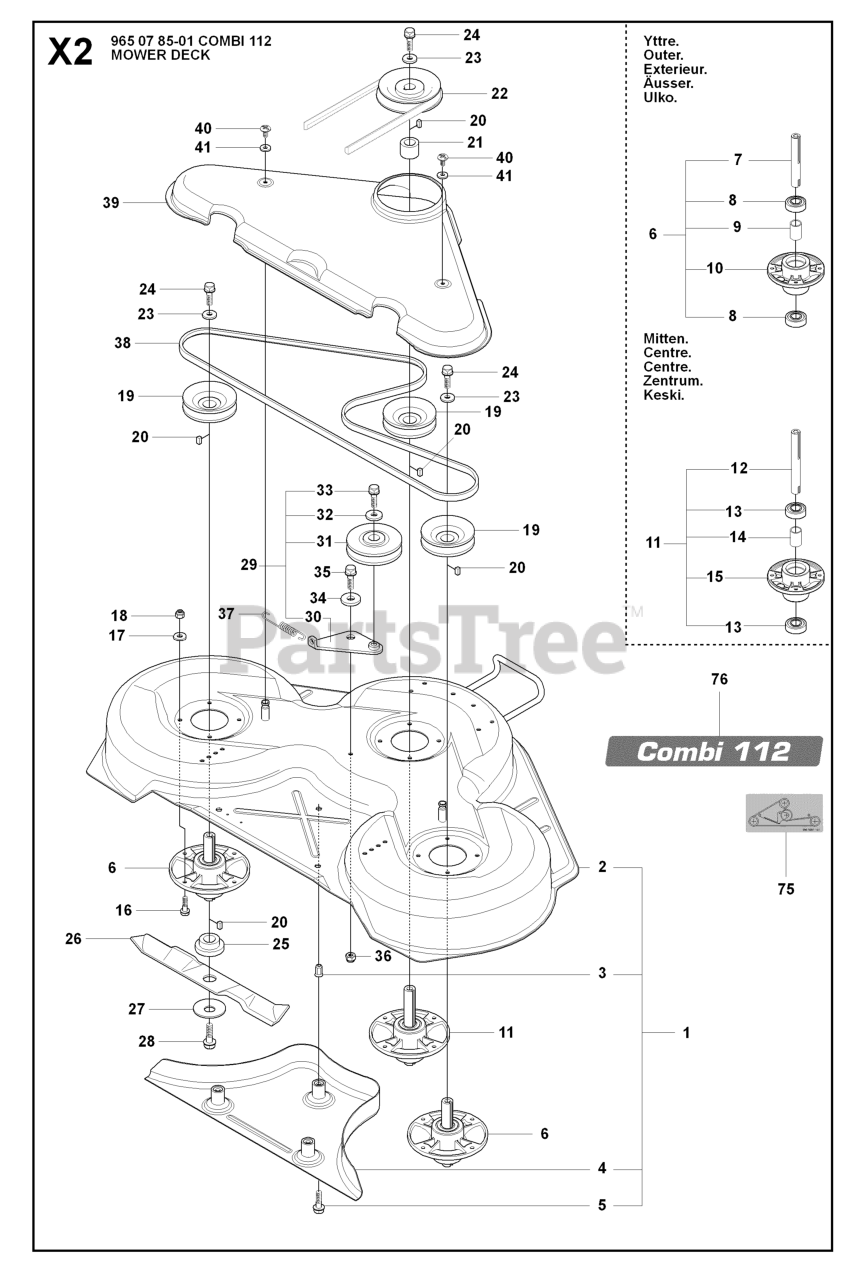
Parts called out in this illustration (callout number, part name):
1	CUTTING DECK C112 GREY RIDER
2	CUTTING DECK ASSY C112 GREY
6	RP SPINDLE ASSY
10	BEARING HOUSING
11	SPINDLE ASSY
15	BEARING HOUSING
17	WASHER BRB 8.4X17
18	LOCKNUT M8
27	WASHER
29	BELT TENSIONER ASSY
30	BELT TENSIONING ARM
34	WASHER
36	LOCKNUT M8
38	BELT
39	BELT COVER
